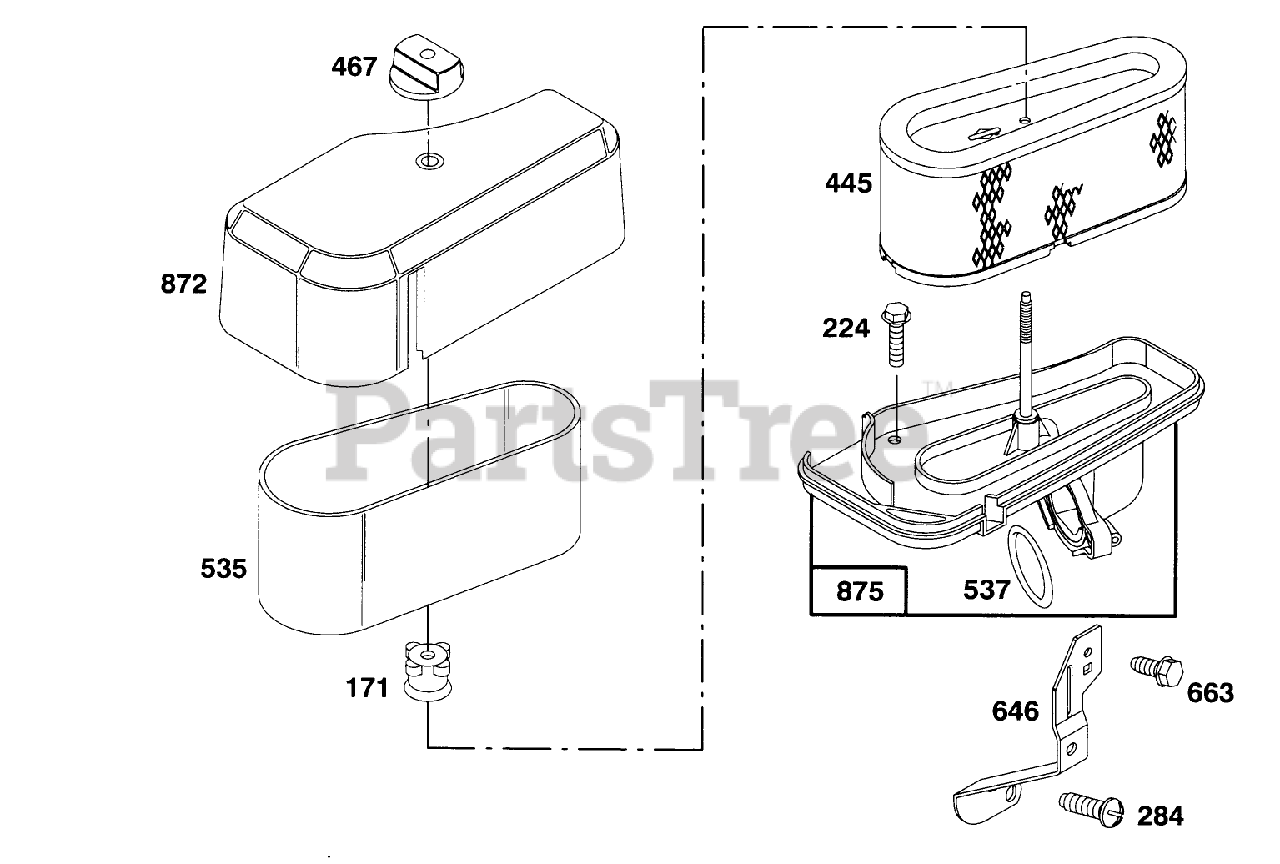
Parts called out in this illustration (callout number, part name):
224	Screw-Sem
284	Screw-Pan Head
445	Filter-Air
535	Filter-Air
537	O-Ring
646	Brace-Air Cleaner
663	Screw
872	Cover-Air Cleaner
875	Base-Air Cleaner
